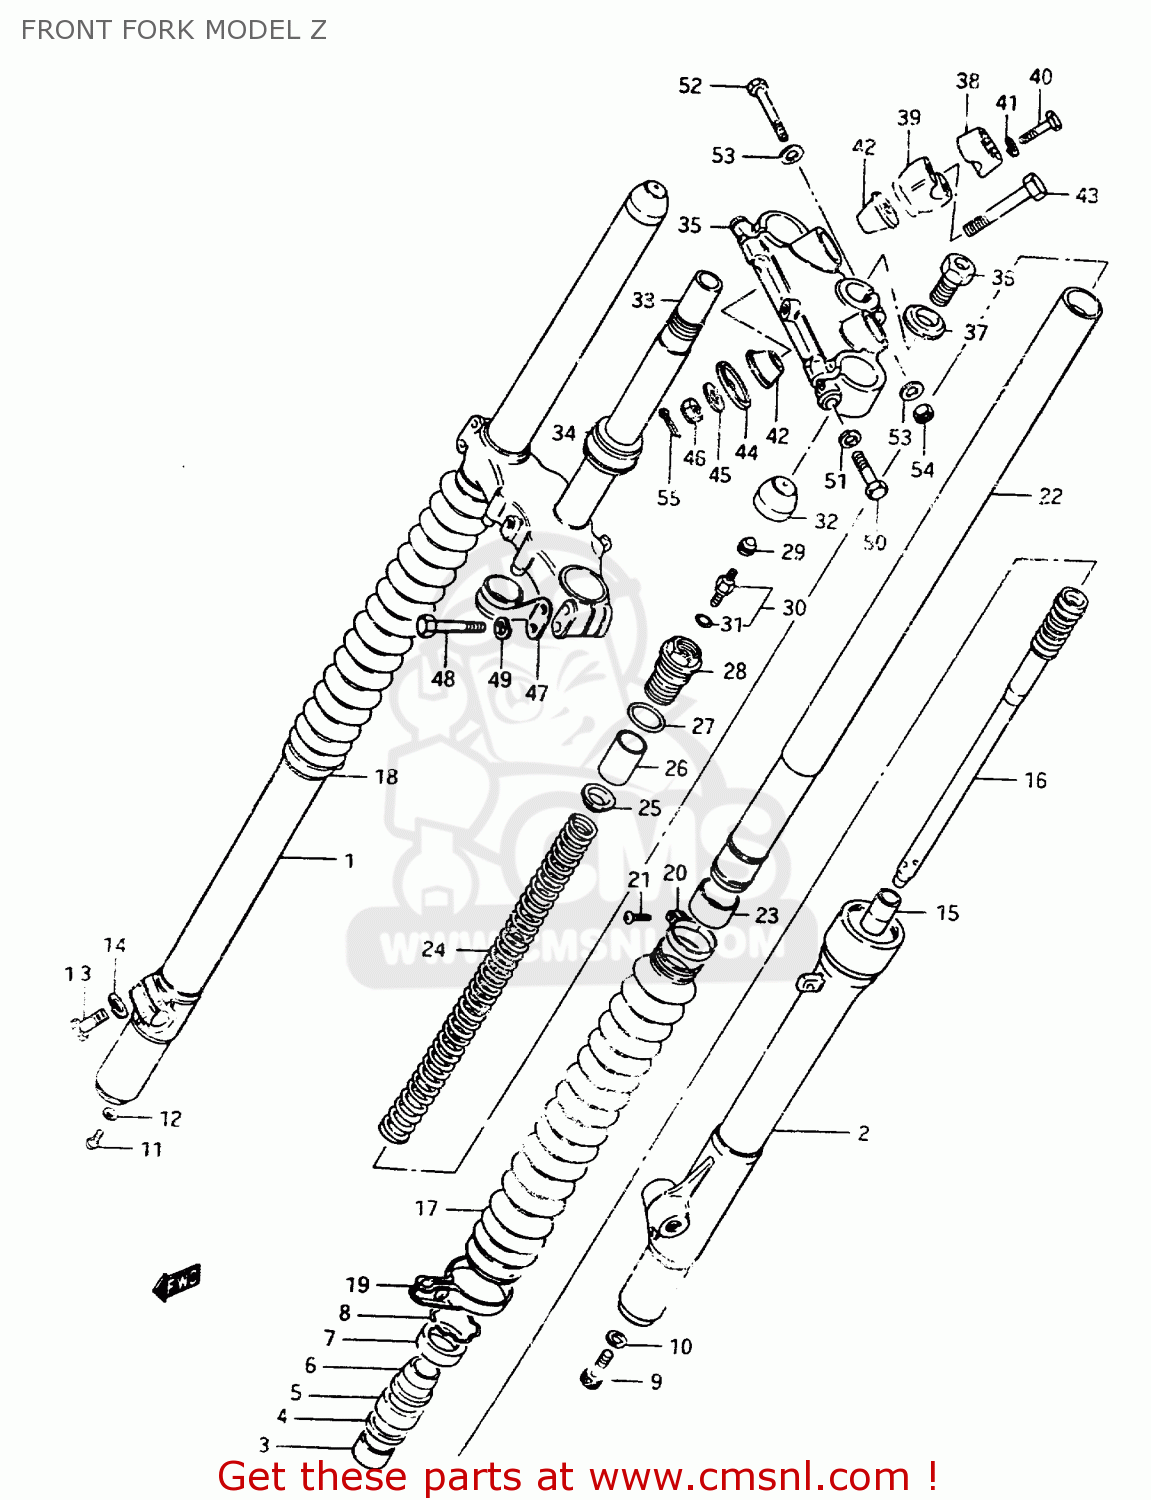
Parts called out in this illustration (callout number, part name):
1	DAMPER SET
2	TUBE,OUTER,LEFT
3	METAL,SLIDE
4	WASHER(40X50X2.3)
5	SEAL,OIL
6	SEAL,DUST
7	CASE,DUST SEAL
8	RING,STOPPER
9	BOLT,CYLINDER
10	GASKET,CYLINDER (NAS)
11	SCREW
12	GASKET,DRAIN,PLUG (NAS)
13	BOLT
14	WASHER,LOCK
15	PIECE,OIL LOCK
16	CYLINDER,FRONT FORK
17	BOOT
18	BAND,FRONT FORK COVER BOOT
19	BAND,FRONT FORK COVER BOOT
20	BAND,BOOT
21	SCREW
22	TUBE,FORK,INNER
23	PISTON
24	SPRING,FRONT FORK
25	GUIDE,FRONT FORK SPRING
26	SPACER,FRONT FORK SPRING
27	O RING
28	CAP,FORK INNER TUBE
29	CAP,VALVE AIR
30	VALVE,FRONT FORK AIR
31	O-RING
32	CAP
33	STEM,STEERING
34	BEARING(30X55X17)
35	HEAD,STEERING STEM
36	BOLT
37	WASHER
38	HOLDER,HANDLEBAR
39	HOLDER,HANDLEBAR,LOWER
40	BOLT
41	WASHER,LOCK
42	CUSHION,HANDLE HOLDER
43	BOLT,HANDLE HOLDER
44	COVER,HANDLEBAR HOLDER
45	WASHER,HANDLEBAR HOLDER
46	NUT
47	CLIP,CABLE
48	BOLT 8X45
49	WASHER,LOCK
50	BOLT
51	WASHER,LOCK
52	BOLT 8X50
53	WASHER
54	NUT
55	PIN 20X20
